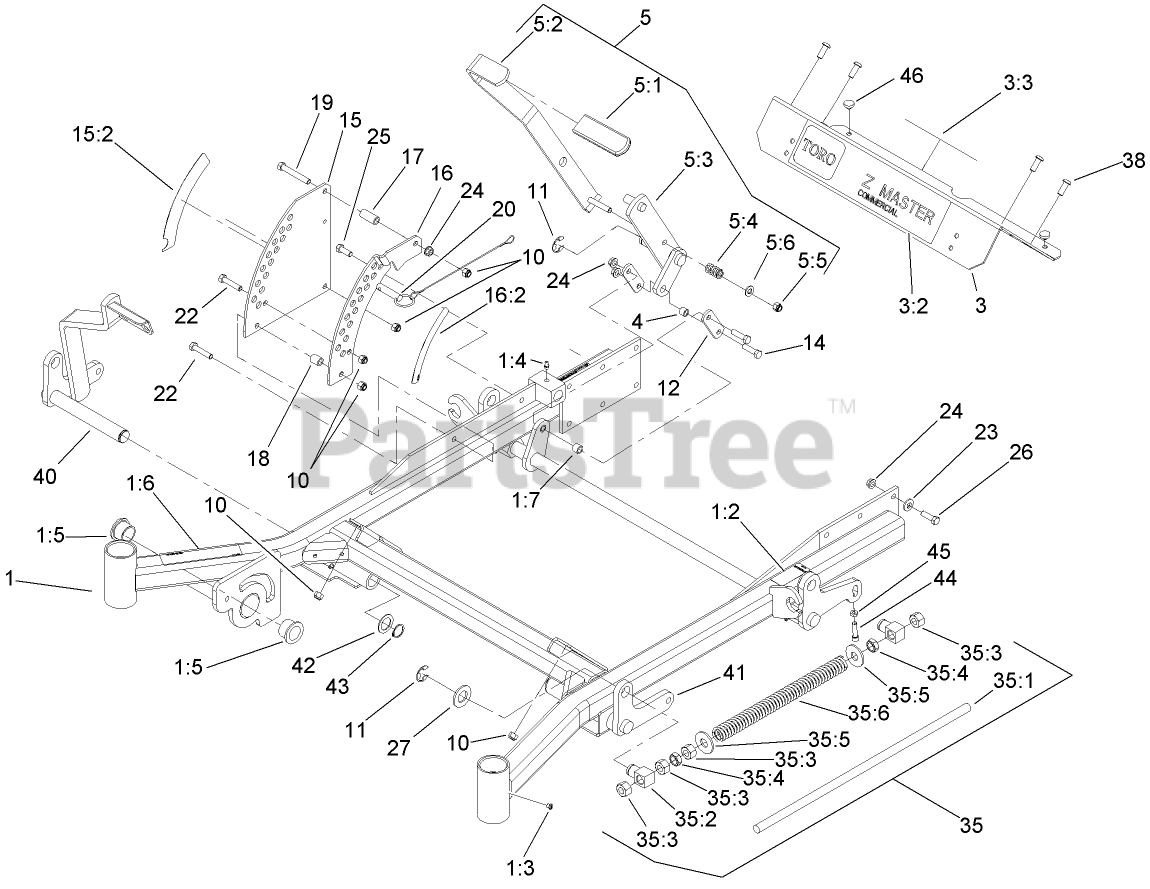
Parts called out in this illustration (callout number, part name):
1	FRAME ASM
1:2	Decal-Brake, Parking
1:4	FITTING-GREASE
1:5	BUSHING
1:6	DECAL-WARNING
1:7	Bushing
3	FOOTREST
3:3	DECAL-WARNING
4	Bushing
5	DECK LIFT HANDLE ASM
5:1	GRIP-LEVER, LIFT
5:2	LEVER-LIFT
5:3	ARM-LIFT, DECK
5:4	SPRING-COMPRESSION
5:5	NUT-LOCK, NI
5:6	WASHER-FLAT
10	NUT-LOCK, NI
11	RING-RETAINING, EXT
12	ARM-LIFT, DECK
14	SCREW-HH
15	PLATE-DECK LIFT, OUTER
15:2	Decal-Height, Deck
16	PLATE-DECK LIFT, INNER
16:2	Decal-Height, Deck
17	BUSHING-LEVER, LIFT
18	BUSHING-LEVER, LIFT
19	SCREW-HH
20	Hitch Pin ASM
22	SCREW-HH
23	WASHER-BELLEVILLE
24	NUT-HHF, WHIZ
25	SCREW-HH
26	SCREW-HH
27	WASHER-FLAT
35	Front Frame Spring ASM
35:1	ROD-LIFT, DECK
35:2	SWIVEL-DECK MOUNT, REAR
35:3	NUT-HEX
35:4	NUT-JAM
35:5	WASHER-FLAT
35:6	SPRING-SUPPORT, DECK
38	SCREW-HSBH
40	LIFT-DECK, RH FRONT
41	LIFT-DECK, LH
42	WASHER-SPACER
43	RING-RETAINING
44	SCREW-HSH
45	NUT-JAM
46	BUMPER
